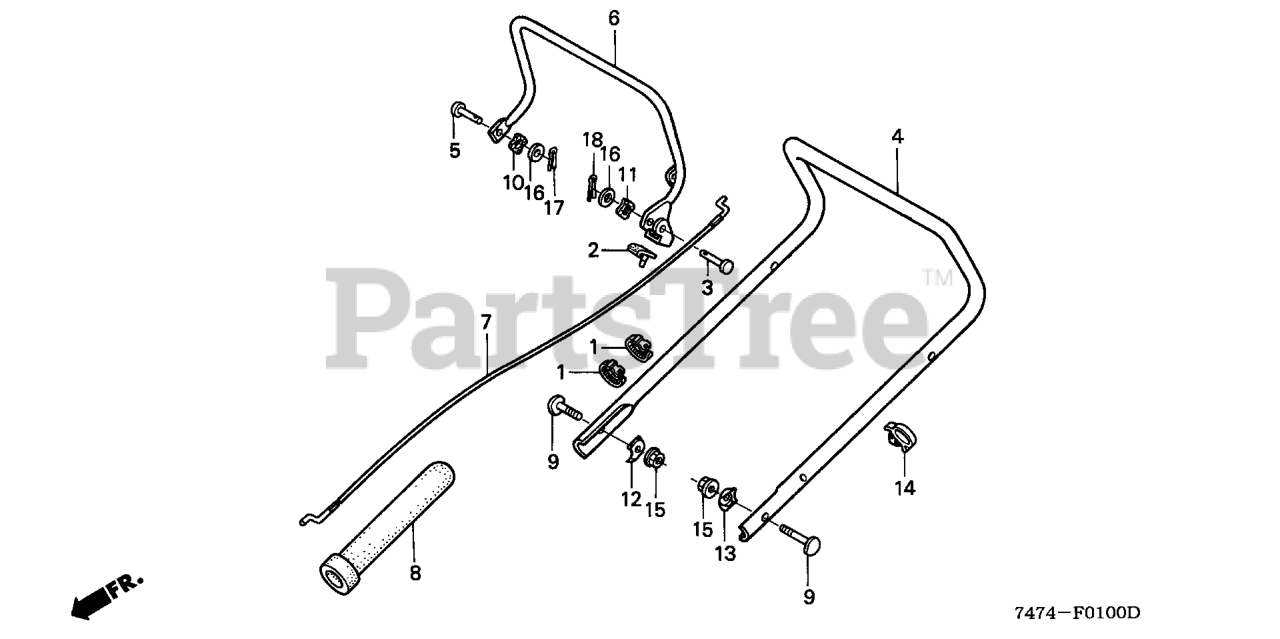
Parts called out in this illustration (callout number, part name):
1	BAND, CABLE
2	RUBBER, STOPPER
3	PIN, MAIN STEP BAR JOINT
4	PIPE, HANDLE (UPPER)
5	PIN (8X30)
6	LEVER, MAIN CLUTCH
7	CABLE, CLUTCH
8	BOOT, CLUTCH CABLE
9	BOLT, HANDLE HOLDER (8X41)
10	WASHER, WAVE (10MM)
11	WASHER, WAVE (10MM)
12	WASHER, FRAME JOINT
13	WASHER, FRAME JOINT
14	CLIP, WIRE HARNESS
15	NUT, FLANGE (8MM)
16	WASHER, PLAIN (8MM)
17	PIN, COTTER (1.6X25)
18	PIN, COTTER (2.0X15)
